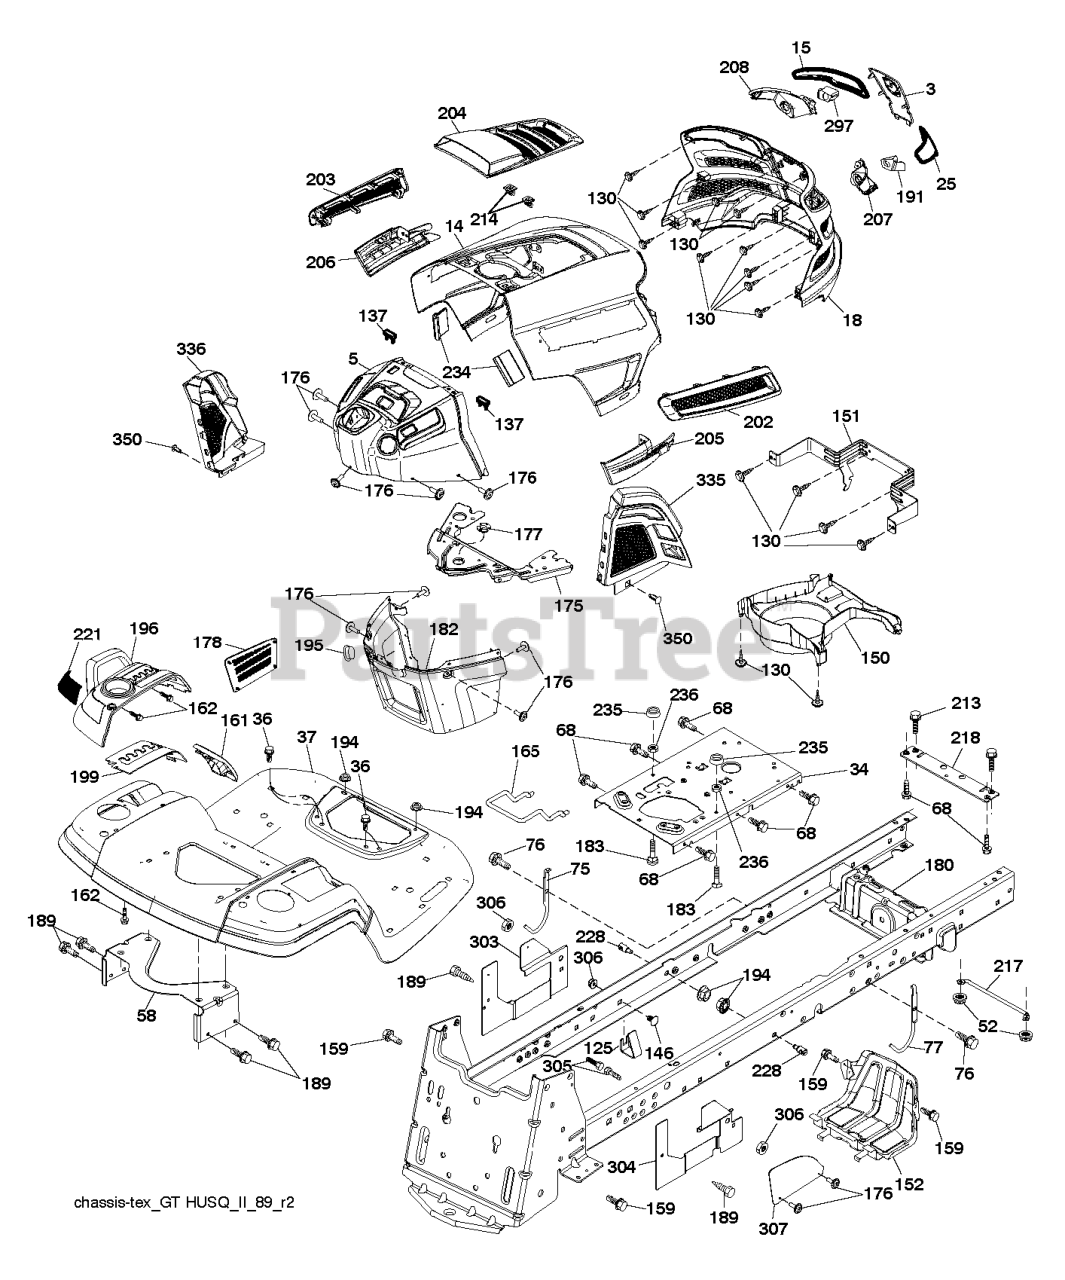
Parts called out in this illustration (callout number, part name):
1	TRANSMISSION SWE
5	WASHER BRB 8.4X17
6	LOCKNUT M8
8	BEARING HOUSING
9	BOLT
10	WASHER BRB 8.4X17
11	LOCKNUT M8
24	PIPE CLAMP
25	COVER PLATE
26	SCREW EHHFM
29	FUEL TANK BUSHING
34	ROD
42	LOCKNUT M6
45	SCREW EHHFM
46	ADJUSTING ROD
47	LOCKNUT M6
48	Screw M10x25
50	LOCKNUT M6
51	HYDRAULIC PIPE
52	HYDRAULIC PIPE
53	PIPE FITTING
56	SCREW
